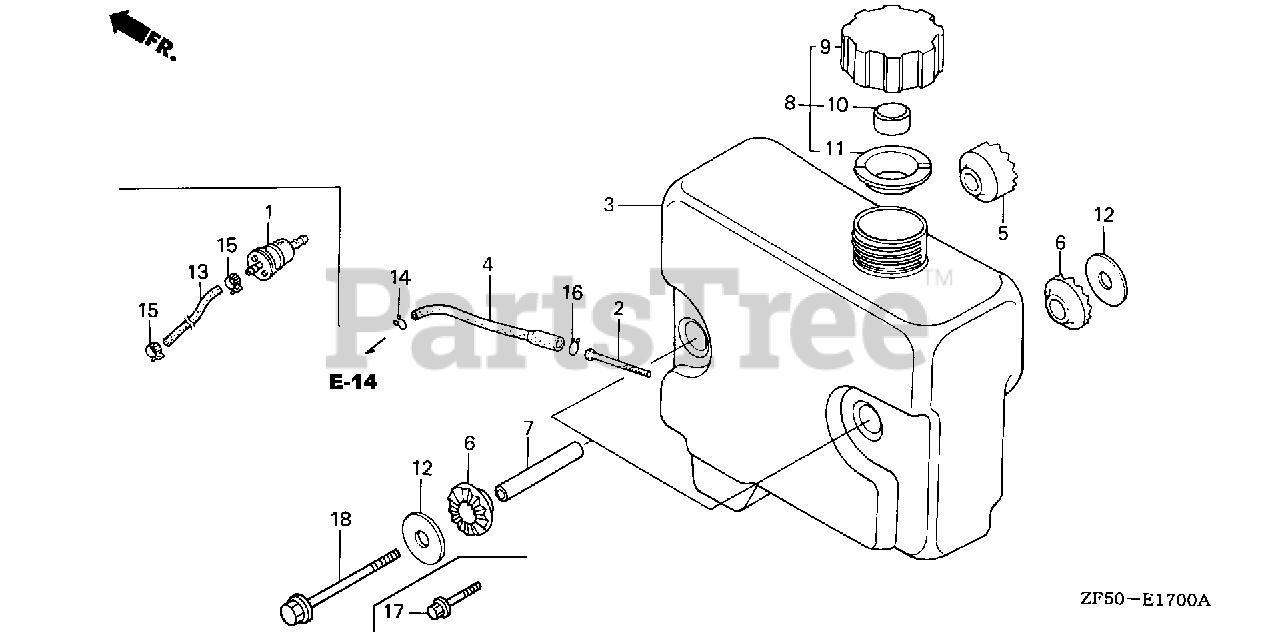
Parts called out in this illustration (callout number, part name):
2	FILTER, FUEL
3	TANK, FUEL
4	TUBE, FUEL
5	RUBBER B, TANK MOUNTING
6	RUBBER B, TANK MOUNTING
7	COLLAR, TANK SETTING
8	CAP ASSY., FUEL TANK
9	BODY, FUEL CAP
10	SPONGE, FUEL CAP BREATHER
11	GASKET, FUEL CAP
12	WASHER, TANK MOUNTING
14	CLIP, TUBE (B8)
16	CLIP, TUBE (C11)
18	BOLT, FLANGE (8X90)
